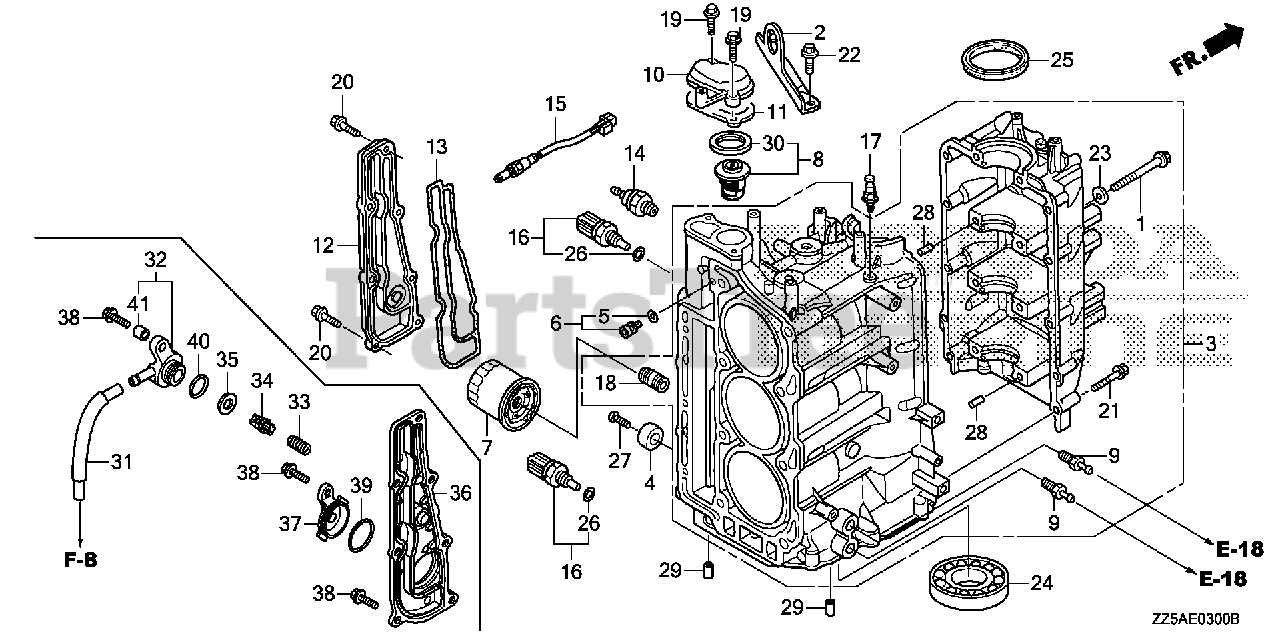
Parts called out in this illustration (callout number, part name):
1	BOLT, FLANGE (8X94)
2	HANGER, ENGINE
3	BLOCK ASSY., CYLINDER *NH8* (DARK GRAY)
4	METAL, ANODE
5	O-RING (4.8X1.9)
6	ORIFICE ASSY., OIL PASSAGE
7	FILTER, OIL (TOYO ROKI)
8	THERMOSTAT ASSY.
9	JOINT, WATER TUBE
10	COVER, THERMOSTAT
11	GASKET, THERMOSTAT COVER
12	COVER, WATER JACKET
13	GASKET, WATER JACKET COVER
14	SWITCH ASSY., OIL PRESSURE
15	SENSOR, OXYGEN
16	SENSOR ASSY., WATER TEMPERATURE
17	BOLT, TIMING BELT ADJUSTING SPRING
18	HOLDER, OIL FILTER
19	BOLT, FLANGE (6X20)
20	BOLT, FLANGE (6X22)
21	BOLT, FLANGE (6X40)
22	BOLT, FLANGE (8X18)
23	WASHER, PLAIN (8MM)
24	BEARING, RADIAL BALL (6005)
25	OIL SEAL (56X70X8)
26	O-RING (9.5X1.5) (HONDA KIKAKI)
27	SCREW, PAN (6X18)
28	PIN, DOWEL (10X12)
29	PIN, DOWEL (6X10)
30	RUBBER, RING
